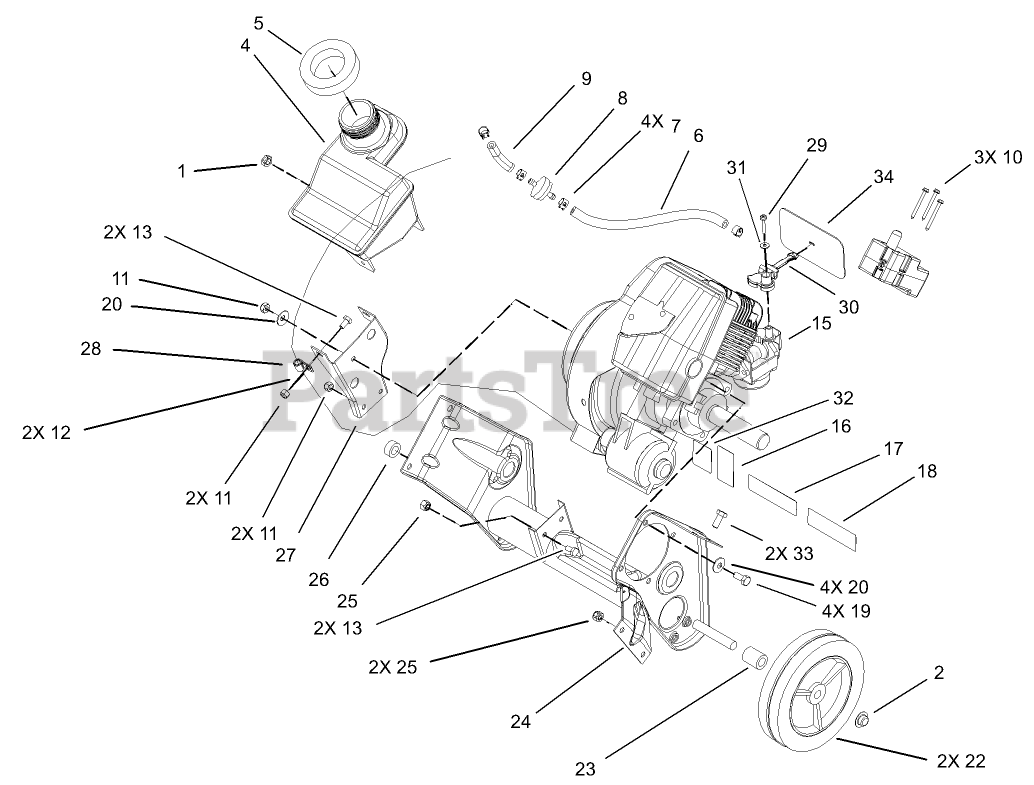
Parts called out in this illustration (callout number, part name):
1	NUT-LOCK, CONE
4	TANK-GAS
5	SEAL-FOAM
6	LINE-FUEL
7	CLAMP-HOSE
8	FILTER-FUEL
10	SCREW-PLASTITE
11	NUT-LOCK, NI
12	WASHER-FLAT
13	SCREW-HH
19	SCREW-HH
20	WASHER-BELLEVILLE
21	NUT-PUSH
22	WHEEL
23	SPACER-WHEEL
25	NUT-LOCK, NI
26	SPACER-WHEEL
27	BRACKET-SUPPORT, RECOIL
28	CLAMP
29	SCREW-PPH, PLASTITE
30	LEVER-CHOKE
31	WASHER-FLAT
33	SCREW-HH
34	SHIELD-HOLE, CHOKE
